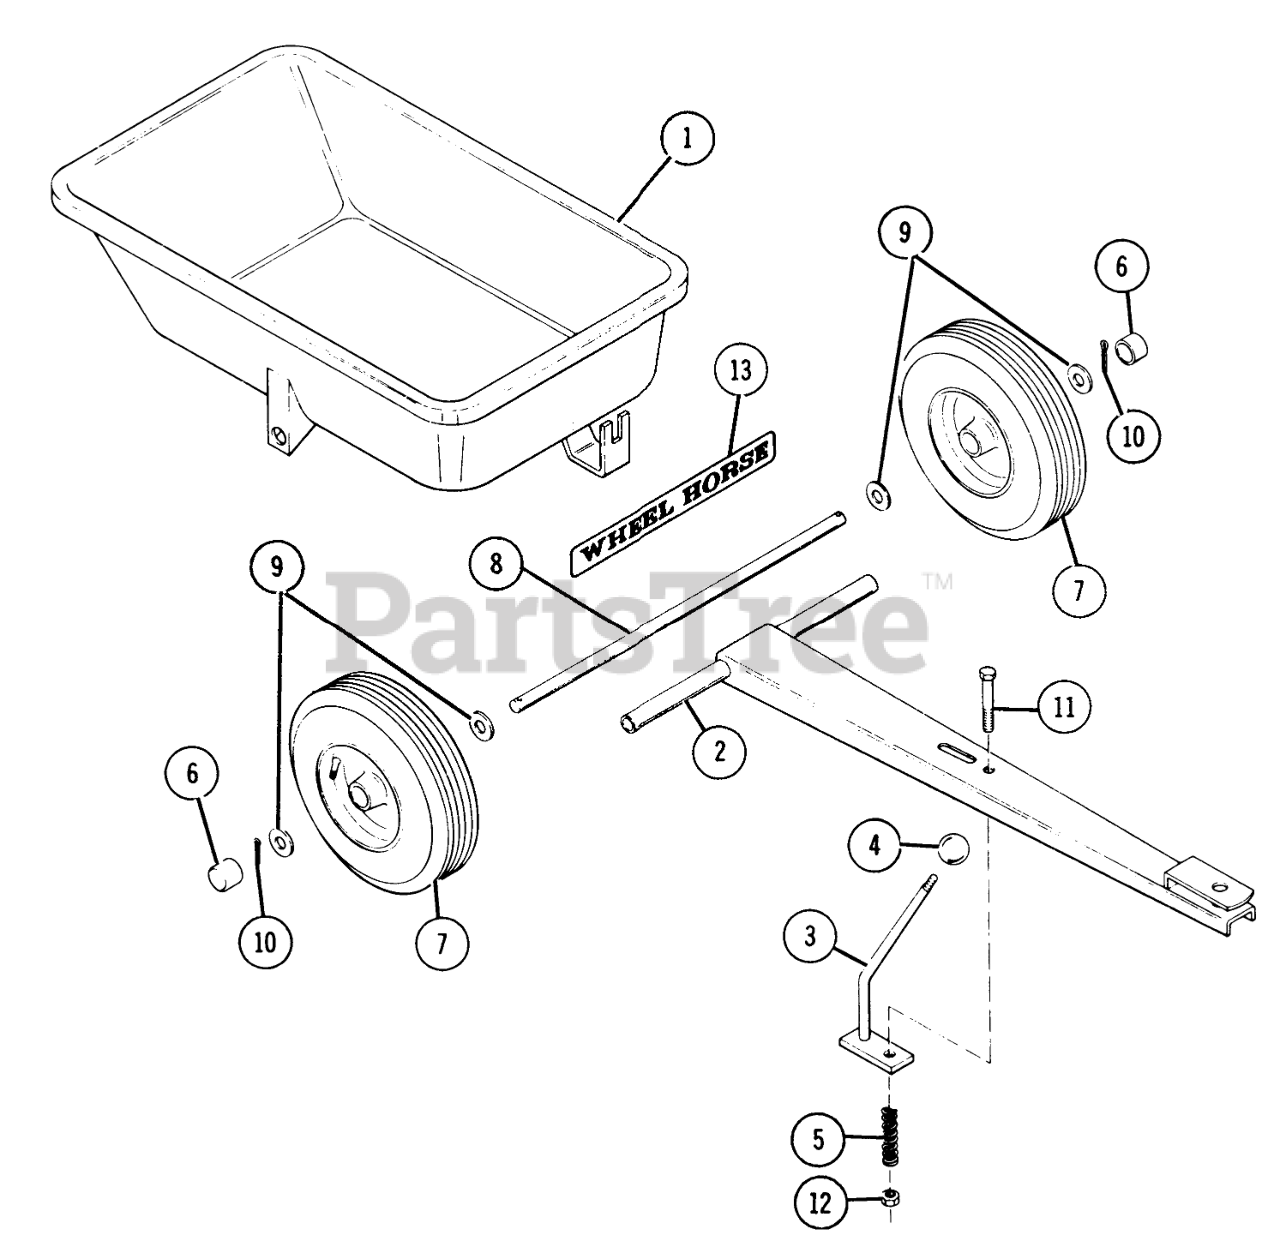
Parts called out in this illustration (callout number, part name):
1	Box Ass-y.
9	WASHER
14	Weight Limit
